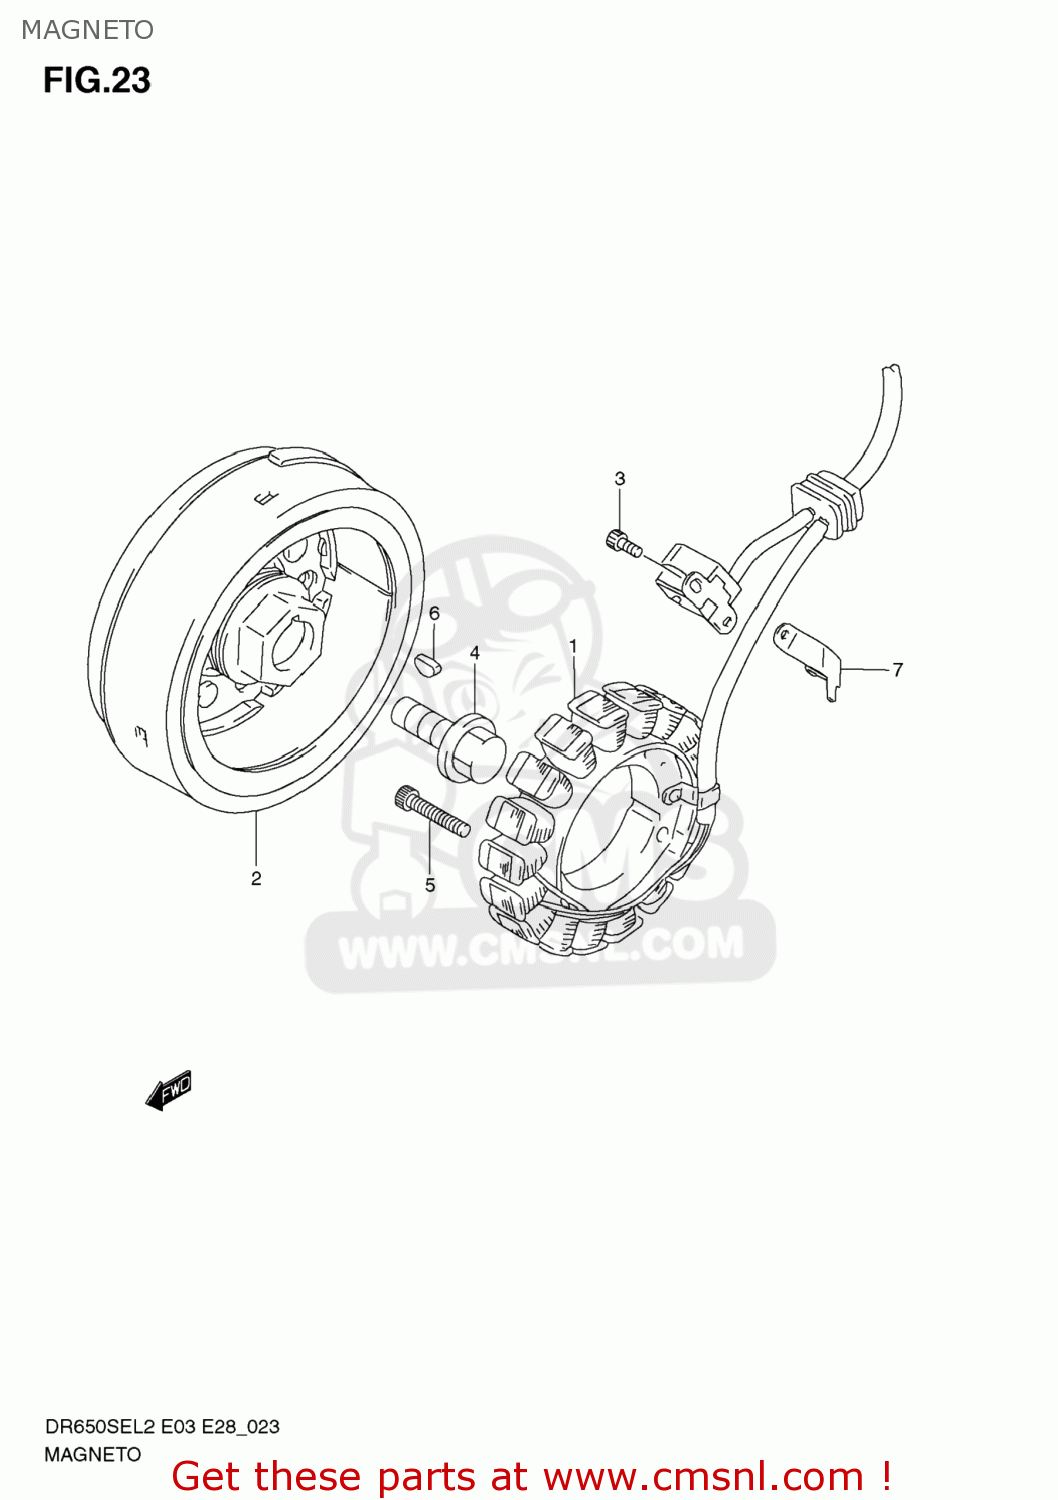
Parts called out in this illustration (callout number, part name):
1	STARTER ASSY
2	ROTOR ASSY
3	BOLT
4	BOLT(14X43)
5	BOLT
6	KEY
7	CLAMP,MAGNETO LEAD
